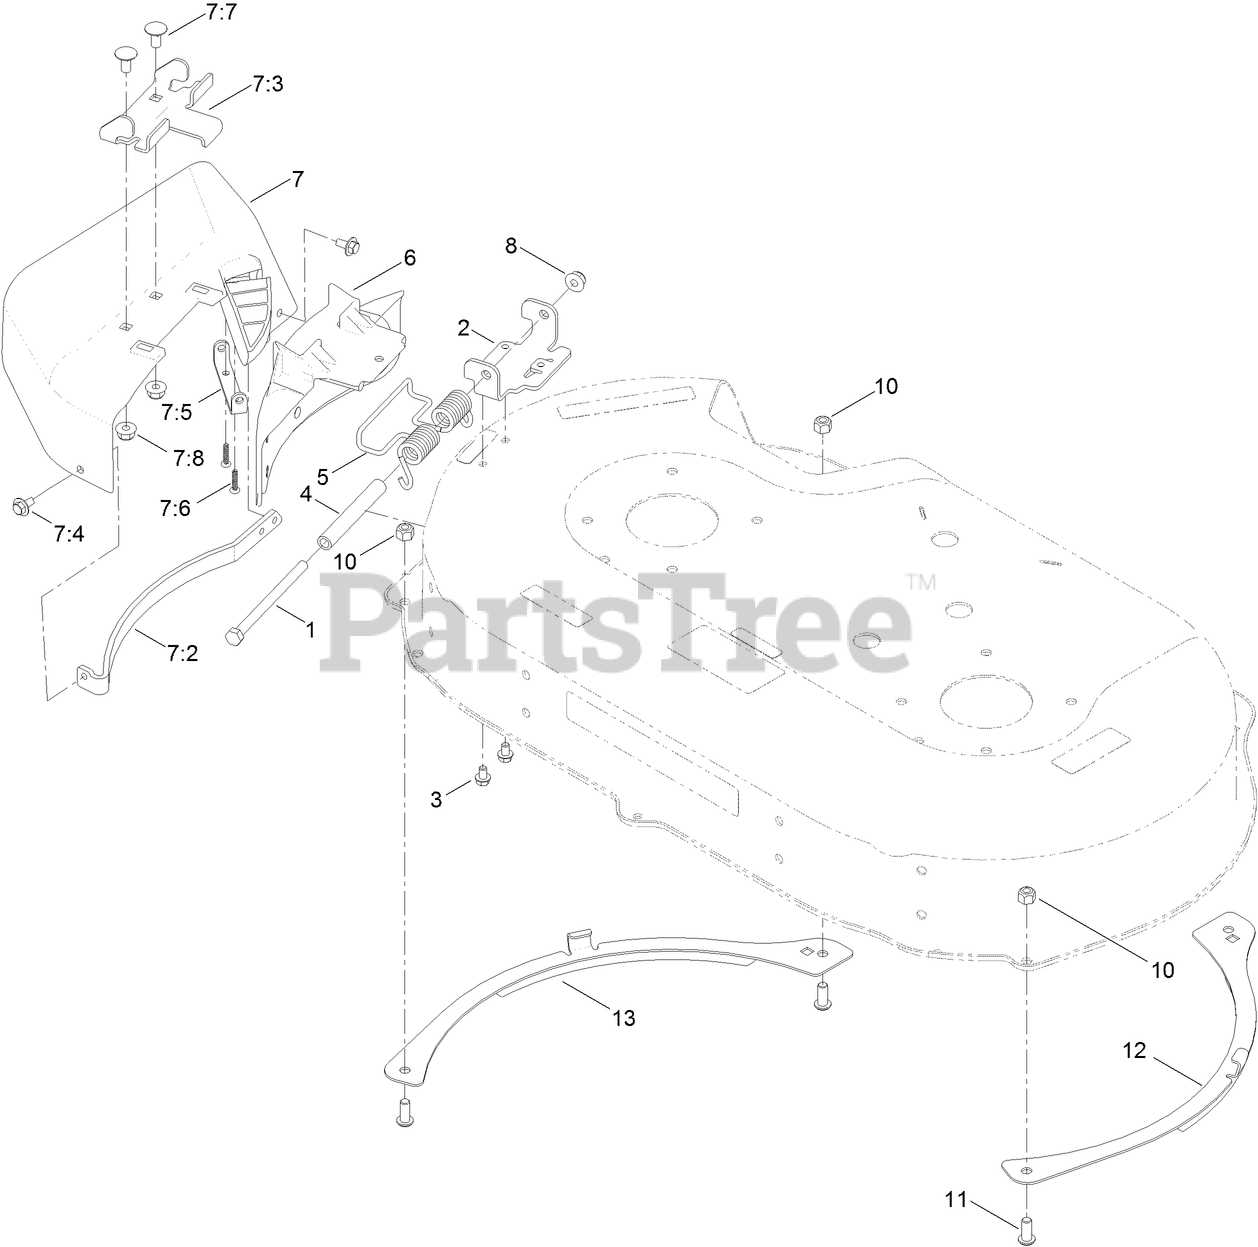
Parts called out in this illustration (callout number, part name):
1	SCREW-HH
3	SCREW-HWH
4	SPACER
5	SPRING-TORSION
6	COVER-DISCHARGE
7	SIDE DISCHARGE CHUTE ASM
7:2	GUARD-CHUTE
7:3	BRACKET-CHUTE
7:4	SCREW-HHFTF
7:5	BRACKET-COVER
7:6	SCREW-PPH
7:7	SCREW-CARR
7:8	NUT-HF, NI
8	NUT-HF, NI
10	NUT-LOCK, NI
11	SCREW-HSBH
